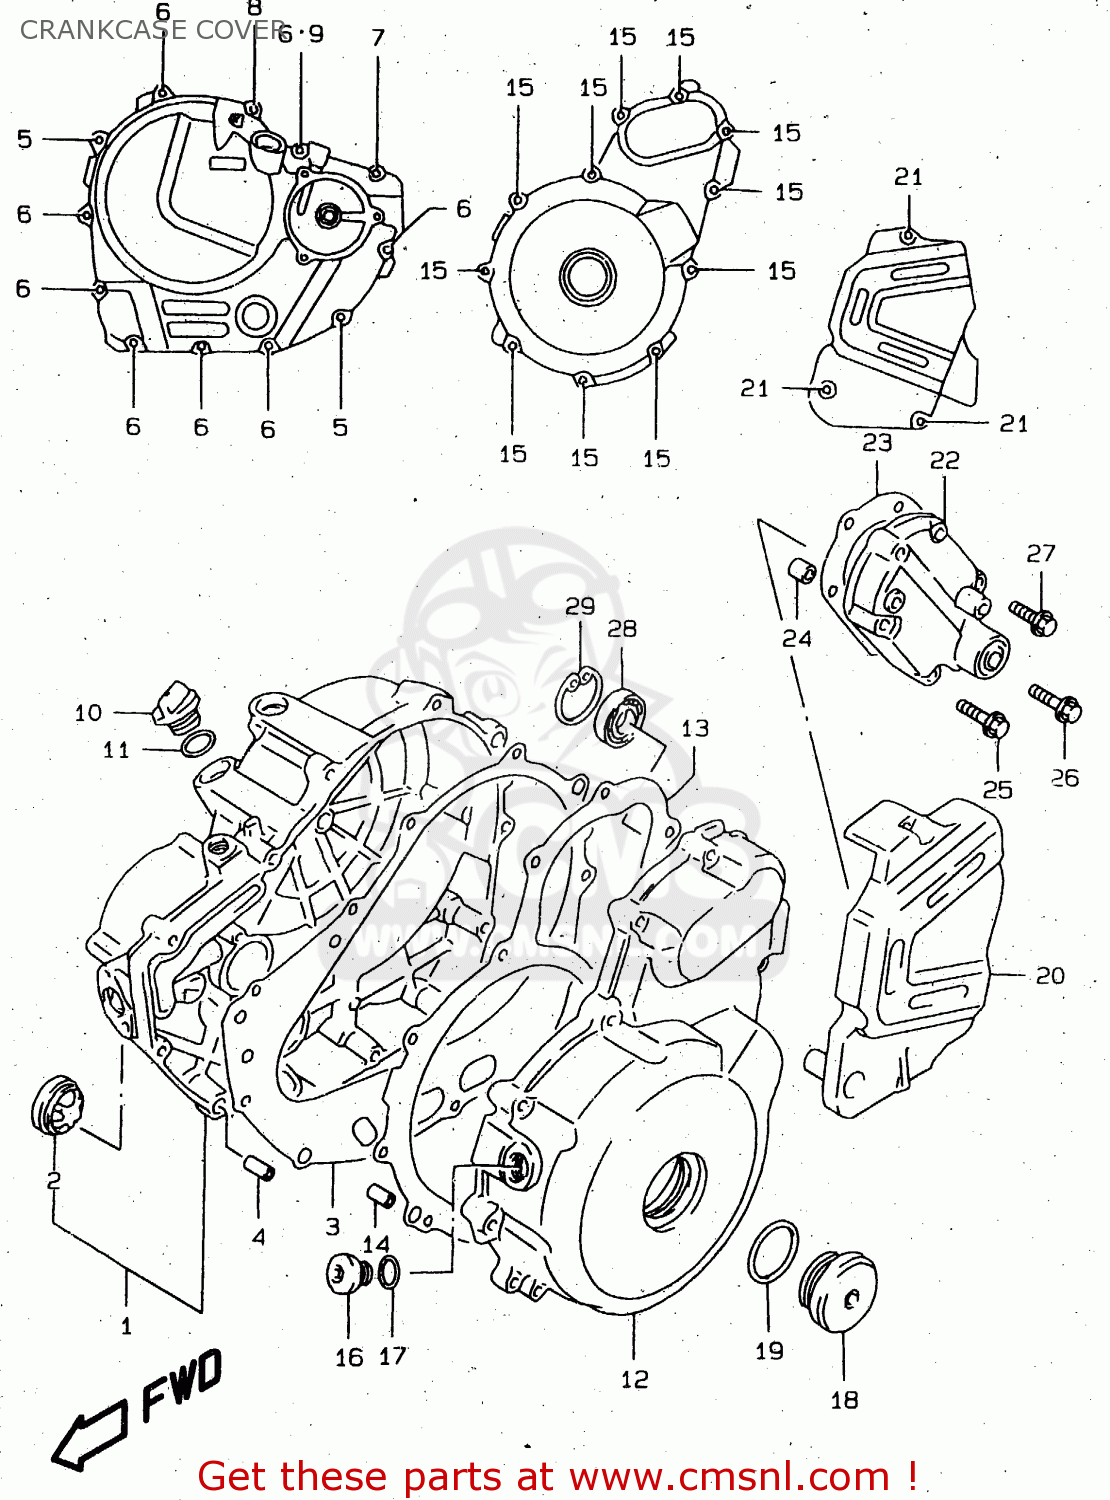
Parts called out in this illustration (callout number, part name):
1	COVER,CLUTCH
2	LENS,OIL LEVEL CHECK
3	GASKET,CLUTCH COVER
4	PIN
5	BOLT
6	BOLT
7	BOLT
8	BOLT
9	GASKET(5.8X11X1.2) (NAS)
10	PLUG
11	O RING(D:3.1,ID:16.8)
12	COVER,MAGNETO
13	GASKET,MAGNETO COVER
14	PIN
15	BOLT
16	PLUG,14X12
17	GASKET(13.8X18.8X4.8) (NAS)
18	PLUG(SILVER)
19	O RING(D:3.1,ID:32.7)
20	COVER,ENGINE SPROCKET
21	BOLT
22	COVER,GEAR SHIFT
23	GASKET,GEAR SHIFT COVER (NAS)
24	PIN
25	BOLT
26	BOLT,G/S SWITC
27	SCREW
28	BEARING(12X28X8)
29	CIRCLIP
